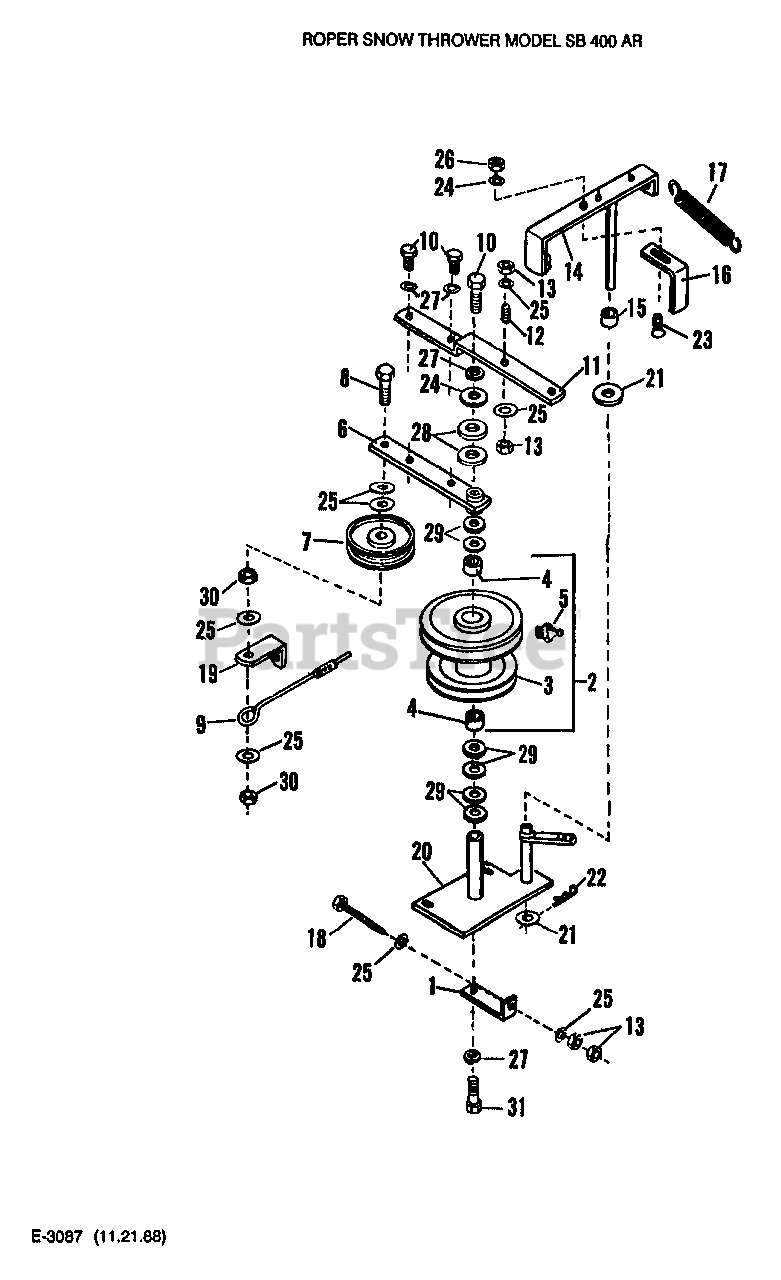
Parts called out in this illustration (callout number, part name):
1	BRACKET-BELT ADJ.
2	PULLEY HOUSING ASSY
3	ASSY-PULLEY HOUSING
5	GREASE FITTING
6	CLUTCH ARM ASSY
7	IDLER PULLEY ASSY
9	WIRE-BELT GAUGE
11	BRACKET-CLUTCH LEVER
12	BRAKE RELEASE STUD
14	ASSY-BELT BRAKE
16	V-BELT POPPER
19	IDLER STOP BRKT
20	PULLEY MTG BRKT
22	HAIR COTTER PIN
26	NUT & WASHER ASSY
28	SCREW 1/4-20 X .875
